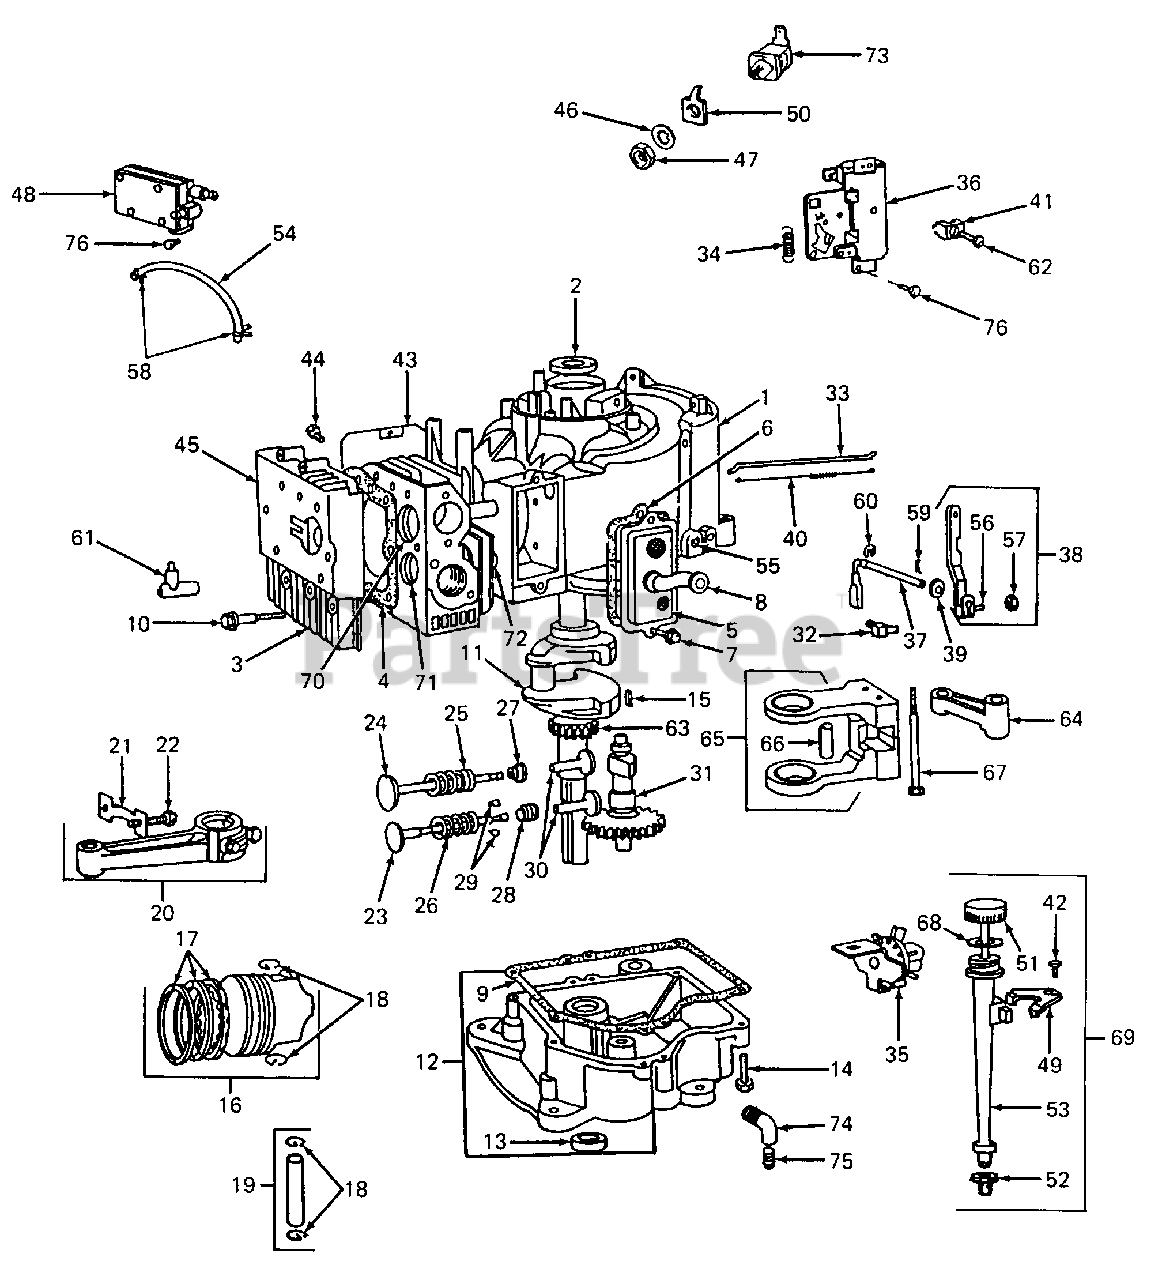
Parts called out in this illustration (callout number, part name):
1	Cylinder Assembly
2	Bushing, Cylinder
3	Head, Cylinder
4	Gasket, Cylinder Head
5	Breather Assembly
6	Gasket, Valve Cover
7	Screw Sem
8	Tube, Breather
9	Gasket, Crankcase Cover 1/64 in. thick
10	Screw, Cylinder Head 3 in. Lg
11	Crankshaft
12	Base, Engine
13	Seal, Oil
14	Screw, Base Mounting Sem
15	Key, Flywheel
16	Piston Assembly Std
17	Piston Ring Set Std
18	Lock, Piston Pin
19	Pin Assembly, Piston Std
20	Connecting Rod Assembly
21	Lock, Connecting Rod Screw
22	Screw, Connecting Rod
23	Valve, Exhaust
24	Valve, Intake
25	Spring, Intake Valve
26	Spring, Exhaust Valve
27	Retainer, Intake Valve
28	Rotocoil, Exhaust Valve
29	Retainer, Exhaust Valve Rotocoil
30	Tappet, Valve
32	Connector, Fuel Pipe
33	Link, Governor
34	Spring, Governor
35	Oil Slinger, Governor Gear & Bracket Assy
36	Plate, Governor Control
37	Crank, Governor 1/4 in. dia.
38	Lever Assy, Governor for 1/4 in. dia. Crank
39	Washer, Governor Lever 1/4 in. ID
40	Spring, Governor Link
41	Clamp, Casing
42	Screw, Clamp Mounting
43	Shield, Cylinder
44	Screw, Cylinder Shield Mounting Sem
45	Cover, Cylinder Head Motor Starting
46	Washer, Lock, Shakeproof
47	Nut, Hex 8-32
48	Pump, Impulse
49	Clamp, Oil Filler Tube
50	Terminal, Spade
51	Cap & Dipstick, Oil Filler
52	Seal, Filler Tube
53	Tube, Oil Filler
54	Pipe, Vent
55	Bushing, Governor Crank 1/4 in. I.D.
56	Bolt, Governor Lever
57	Nut, Hex 10-24
58	Clamp, Fuel Pipe
59	Cotter, Hair Pin
60	Retainer, E-Ring
61	Elbow, Spark Plug
62	Screw Sem
63	Gear, Timing
64	Link, Counterweight
65	Counterweight Assy
66	Pin, Counterweight
67	Screw, Counterweight
68	Seal, Filler Cap
69	Filler Group, Oil
70	Seat, Intake Valve Std
71	Seat, Exhaust Valve Std
72	Guide, Exhaust Valve
73	Insulator Assy
74	Tube, Oil Drain
75	Plug, 3/8-18 Znp H/Hd Auto Pipe Oil Drain
76	Screw Sem
